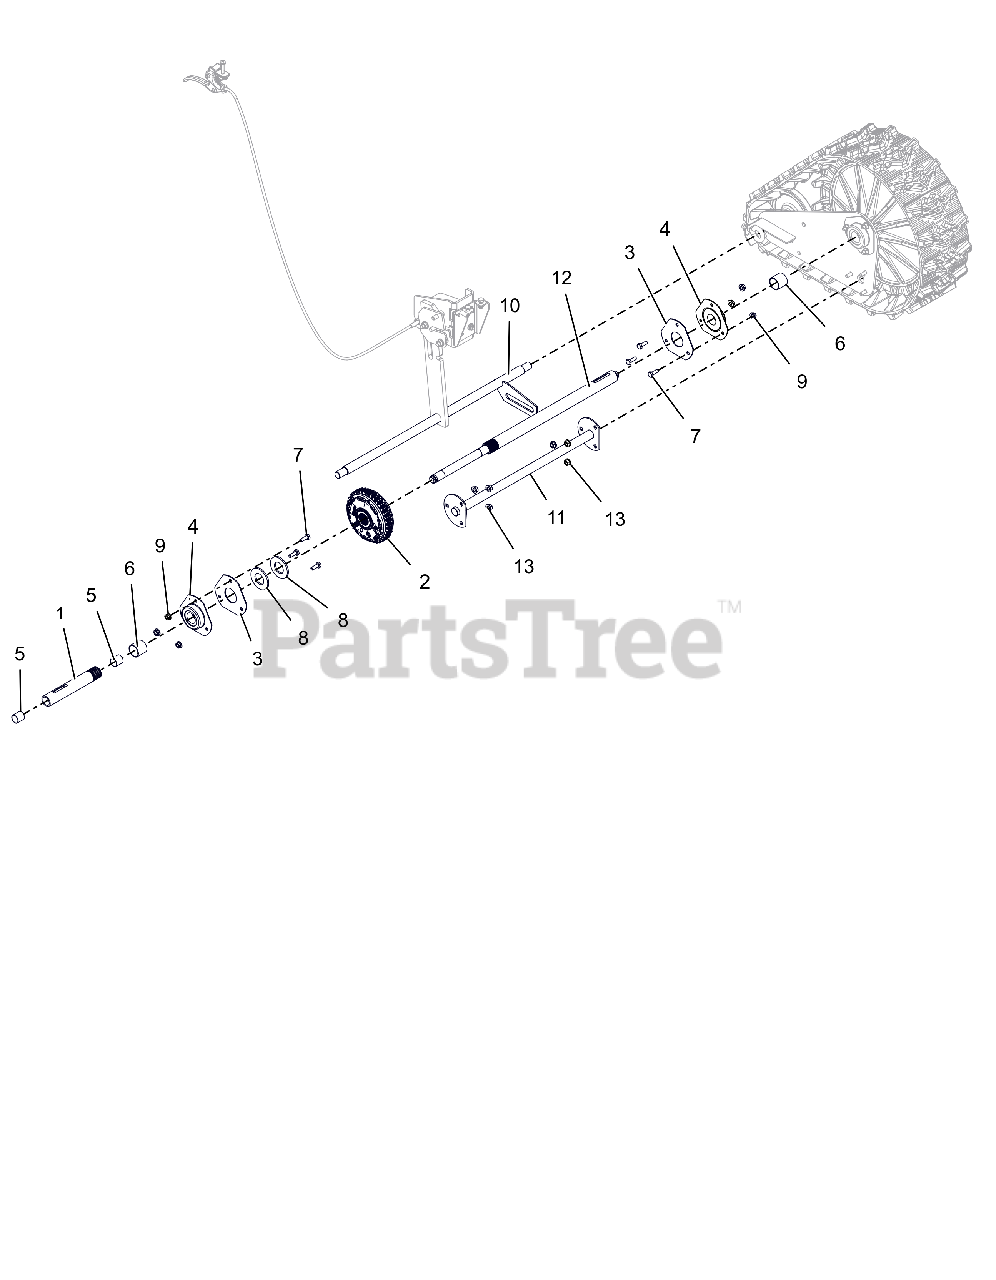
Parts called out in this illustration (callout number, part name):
1	AXLE, SHORT-W/BUSHINGS
2	DIFFERENTIAL, AUTOMATIC
3	PLATE, BEARING SPACER
4	BRG-FLG 1.003/1.000 3 BOLT
5	BSHG-SLV .706X.764X.75 BRZ
6	BSHG-SLV, 1.012X1.125X1.00
7	@BLT-HEX .25-20X.75 GR5 YWZC
8	WSHR-FL-STL- 1.062X2.0X.134 YZ
9	@NUT-LK-CTR-FLG .25-20 YWZC
10	AXLE, REAR-BWT WLDMT
11	SUPPORT, FRONT-BWT
12	AXLE, LONG-TRACK DIFFERENTIAL
13	@NUT-LK-TOP-FLG .25-20 YWZC
